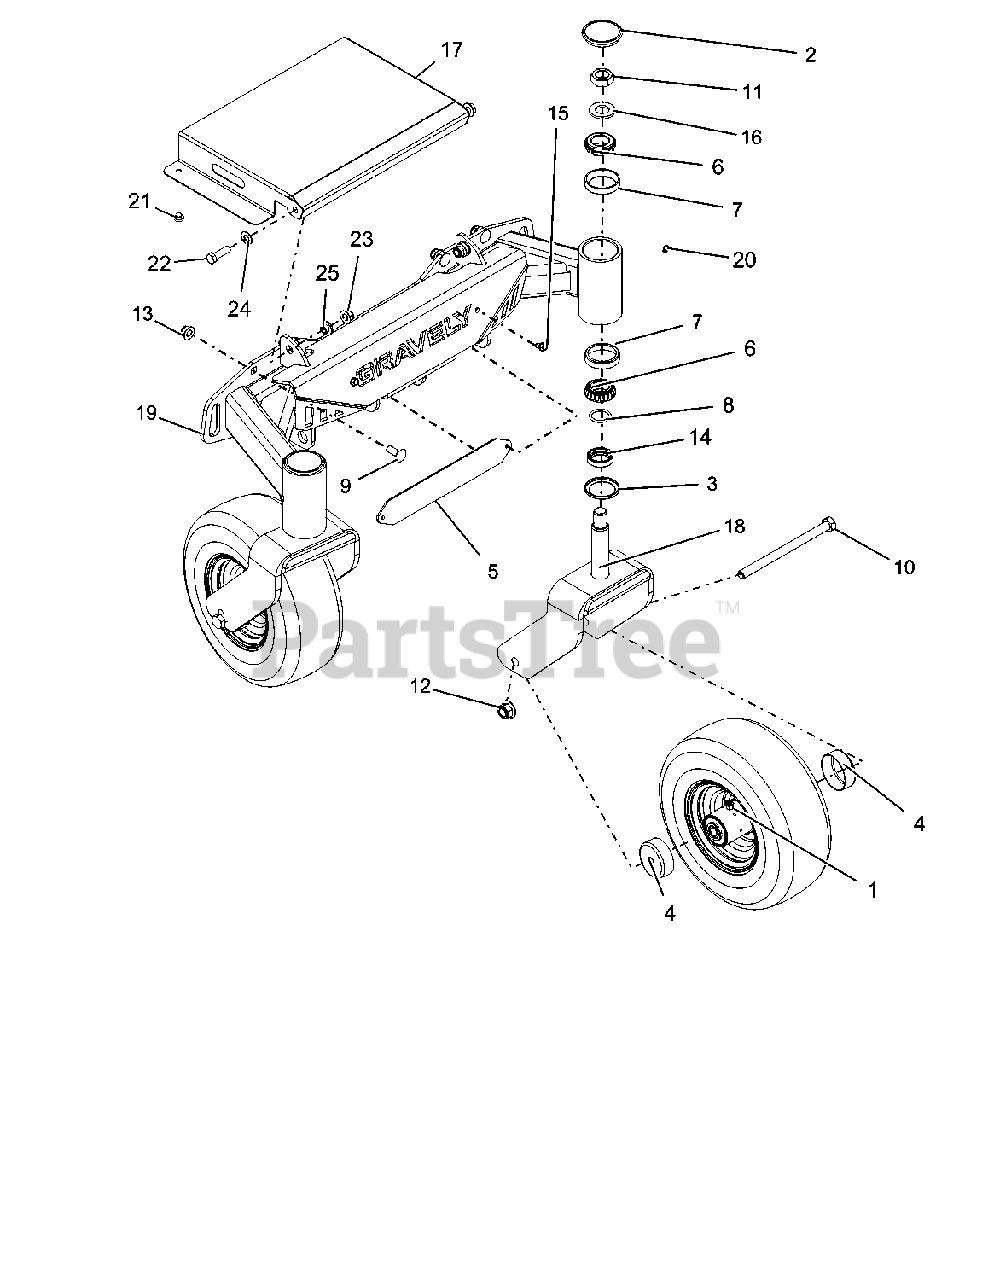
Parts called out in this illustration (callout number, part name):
1	ASM, WHL/TIRE 11X4.00-5
2	CAP, DUST
3	BEARING SEAL 1.5 X 2 X .18
4	SHIELD, WHEEL BEARING
5	BACK, NAMEPLATE
6	BRG-CONE 1.0X.58
7	BRG-CUP1.980X.420
8	O-RING 1.000X1.250X
9	@BLT-RDHDSQNK .38-16X1.00 G5YZ
10	@BLT-HEX .50-13X7.00 GR5 YWZC
11	NUT-JAM TOPLK .75-16 YWZC
12	@NUT-LK-NYL-FLG .50-13 YWZC
13	@NUT-LK-NYL-FLG .38-16 YWZC
14	SPCR, CASTER FORK (1.00)
15	SCR-TAP .25-20X.50 HWH TR YWZ
16	@WSHR-FL-STL.812X1.50X.135YWZC
17	SHIELD, HEAT
18	WLDMT, FRONT FORK
19	WLDMT, FRONT AXLE
20	FTG, .25-28 FLUSH MNT GREASE
21	BUMPER GROMMET
22	@BLT-HEX .38-16X1.25 GR5 YWZC
23	@NUT-LK-NYL-FLG .38-16 YWZC
24	@WSHR-FL-STL.406X.812X.065 YWZ
25	BSHG-FLG .32X.500X.344X.880
